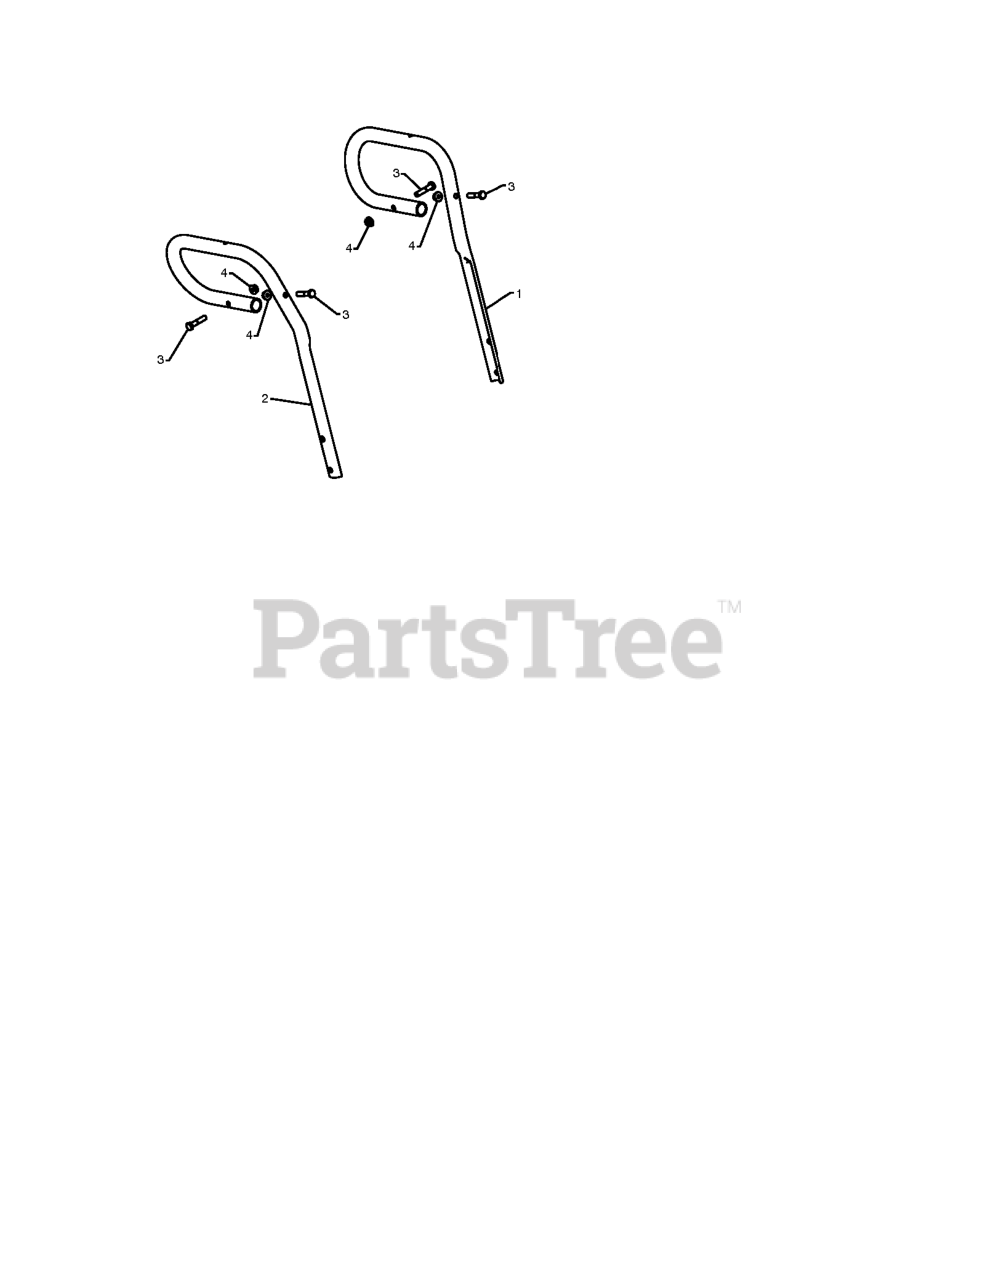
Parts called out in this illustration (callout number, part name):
1	TUBE.HANDLE.LOOP.LH.GRAY
2	TUBE.HANDLE.LOOP.RH.GREY
3	HEX BOLT
4	NUT.LOCK.5/16-18
